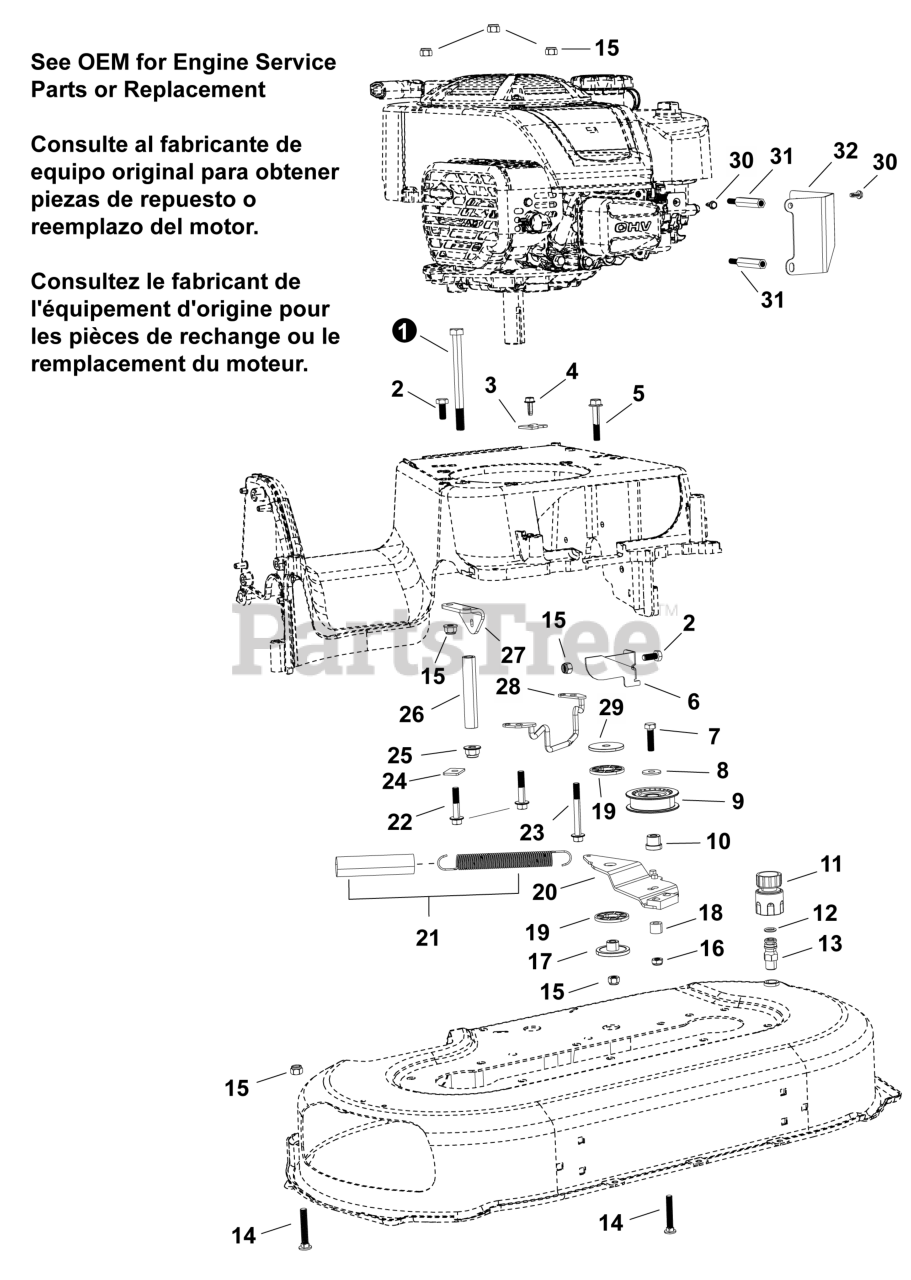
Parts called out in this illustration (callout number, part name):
3	PLATE, BRAKE CABLE
6	PLATE, LIMITER
9	TENSIONER
10	BUSHING, TENSIONER
11	ADAPTOR, HOSE
13	PORT, HOSE
17	MOUNT, BRAKE
19	ANTI-FRICTION PAD
21	SPRING, BRAKE TENSION
27	MOUNTING PLATE, EXTENSION SPRING
28	GUARD, BELT
29	WASHER, BRAKE
32	GUARD, ENGINE
